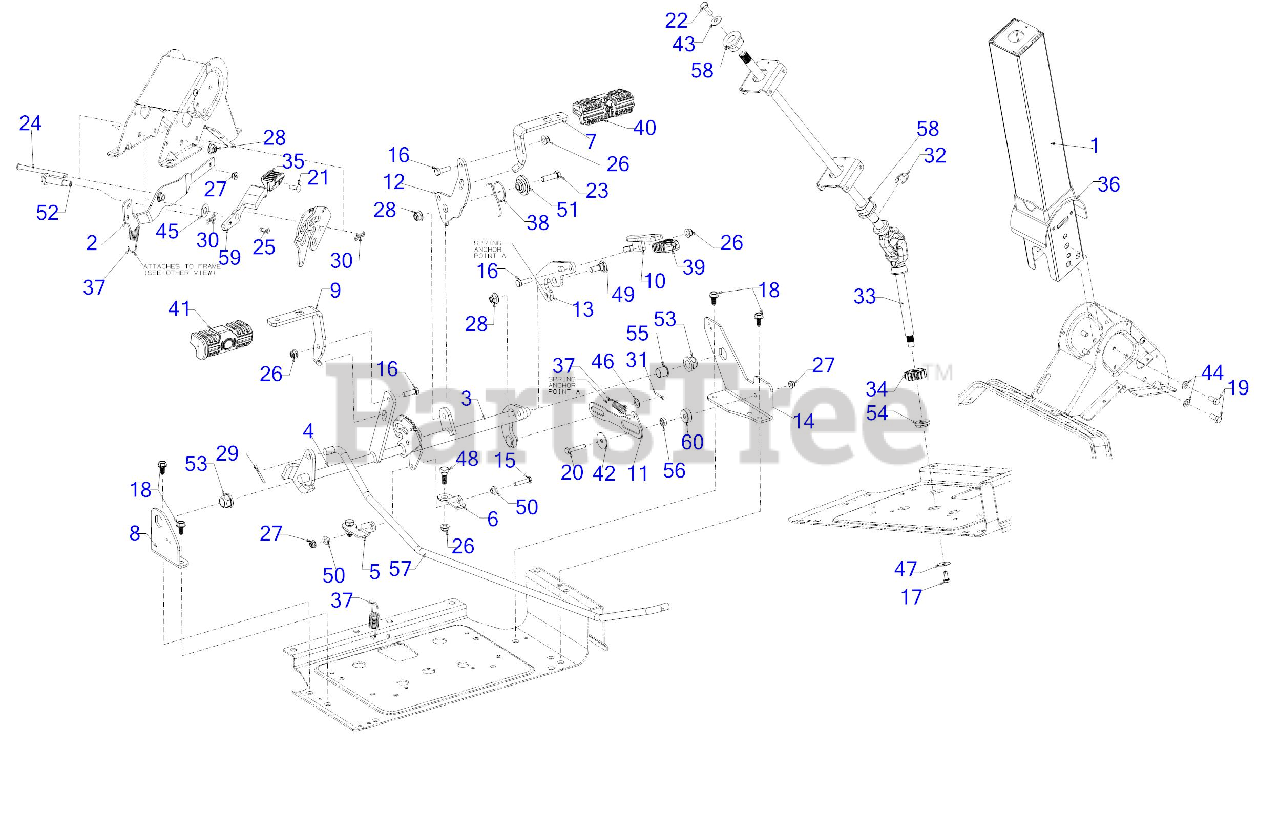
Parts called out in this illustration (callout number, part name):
3	DRIVE PEDAL SHAFT ASSEMBLY
4	BRAKE SHAFT ASSEMBLY
11	NEUTRAL RETURN LINK
12	FORWARD PEDAL BRACKET
13	REVERSE PEDAL PIVOT PLATE
15	HEX SCREW 1/4-20 x 1.25
16	SCREW 5/16-18 x 1.0 GR5
17	SCREW 1/4-20 x .62 SPEC GR5
18	SCREW 5/16-18 x .750
19	SCREW 5/16-18 x .62 GR5
20	SCREW 1/4-20 x 1.50 GR.5
21	SCREW 1/4-20 x .75 GR5
22	SCREW 5/16-24 x .875 GR5
23	SCREW 3/8-16 x 1.25 GR5
24	CLEVIS PIN 5/16 x 4.135
25	CLEVIS PIN .224 x .625
26	FLANGE LOCK NUT 5/16-18
27	FLANGE LOCK NUT
29	COTTER PIN-5/32 DIA
30	BOW TIE COTTER PIN 1/4-5/16
31	COTTER PIN
32	E-RING
33	STEERING SHAFT ASSEMBLY
34	STEERING GEAR 14T
35	CRUISE TILT KNOB
36	LOWER STEERING COLUMN COVER
37	EXTENSION SPRING
38	TORSION SPRING
39	REVERSE PEDAL PAD
40	FORWARD PEDAL PAD
41	BRAKE PEDAL PAD
42	FLAT WASHER
43	BELL WASHER .337 X.867 x .057
44	FLAT WASHER
45	FLAT WASHER .510 x 1.00 x .060
46	WASHER THRUST .375X.70X.030
47	FLAT WASHER
48	SHOULDER SCREW .437
49	SHOULDER SCREW
50	SHOULDER SPACER
51	SHOULDER SPACER 1.50X.38X.38
52	SHOULDER SCREW .496X1.44 3/8-16
53	FLANGE BEARING
54	HEX FLANGE BEARING 7/16
55	NYLINER BEARING
56	BALL BEARING .25 X .625
57	FRONT BRAKE ROD
58	FLANGE BEARING
59	CRUISE LATCH
60	SPACER .267X1.00X.36
